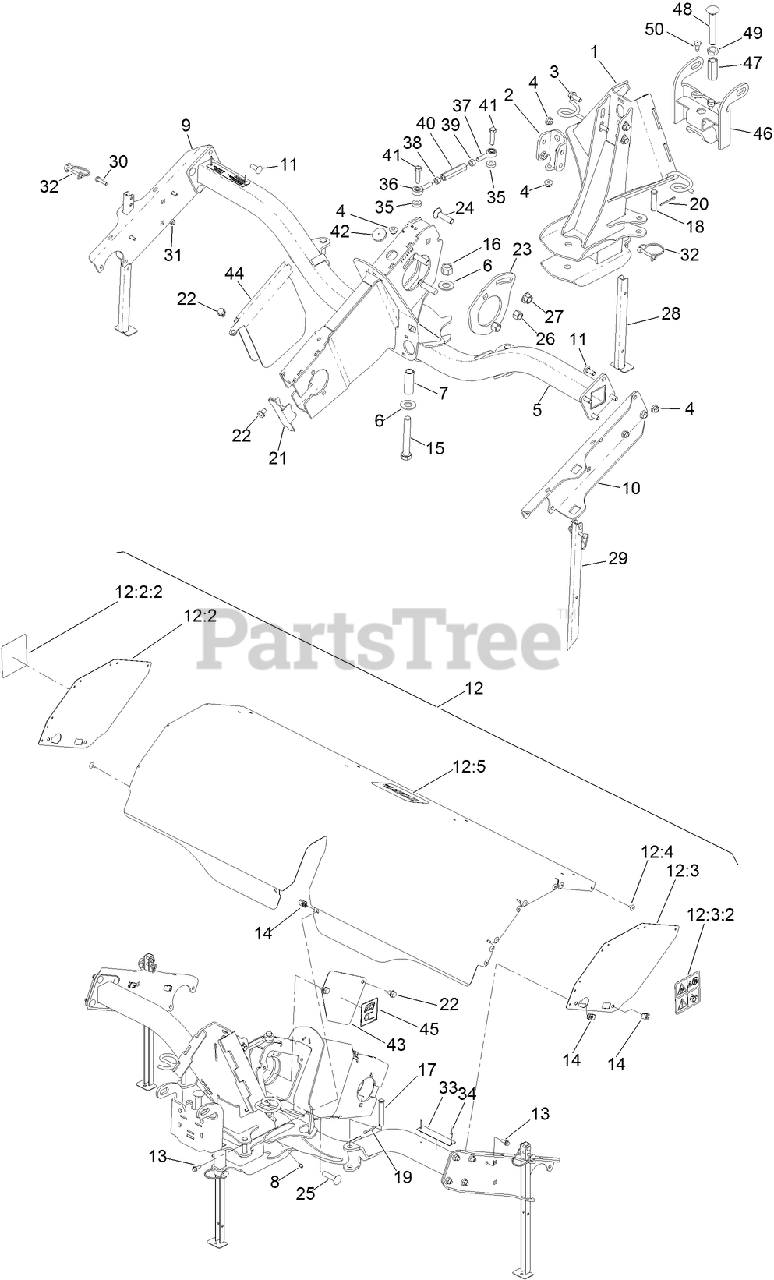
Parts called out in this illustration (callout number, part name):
1	PUSH FRAME ASM
2	CHANNEL-COUPLER
3	SCREW-HHF
4	NUT-HF, NI
5	BROOM DRIVE ASM
6	Washer-Pinion
7	SPACER
8	FITTING-GREASE
9	BRACKET-BRISTLE CARRIER, RH
10	BRACKET-BRISTLE CARRIER, LH
11	SCREW-CARR
12	BROOM SHROUD ASM
12:2	LH END CAP ASM
12:2:2	DECAL-WARNING
12:3	RH END CAP ASM
12:3:2	DECAL-WARNING
12:4	RIVET-POP
12:5	DECAL
13	SCREW-HHF
15	SCREW-HH
16	NUT-LOCK, NI
17	PIN-CLEVIS
18	PIN-CLEVIS
19	PIN-COTTER
20	PIN-COTTER
22	SCREW-HWH,THD ROLL
23	PLATE-MOTOR
24	SCREW-CARR
25	SCREW-CARR
26	NUT-HEX
27	NUT-LOCK
28	LEG-STAND
29	LEG-STAND
30	SCREW-HH
31	NUT-LOCK, NI
32	PIN-HITCH
33	PLATE-MODEL
34	RIVET
35	SPACER
36	BALLJOINT
37	BEARING-END, ROD
38	NUT-HEX
39	NUT-HEX, LH
40	TURNBUCKLE
41	SCREW-HH
42	GROMMET-PLUG
43	PLATE-COVER
44	BRACKET-COVER
45	DECAL-CHAIN ADJUST
46	LOCK BRACKET ASM
47	HEX-THREADED
48	BOLT-CARRIAGE
49	NUT-JAM
50	BUMPER-RUBBER
